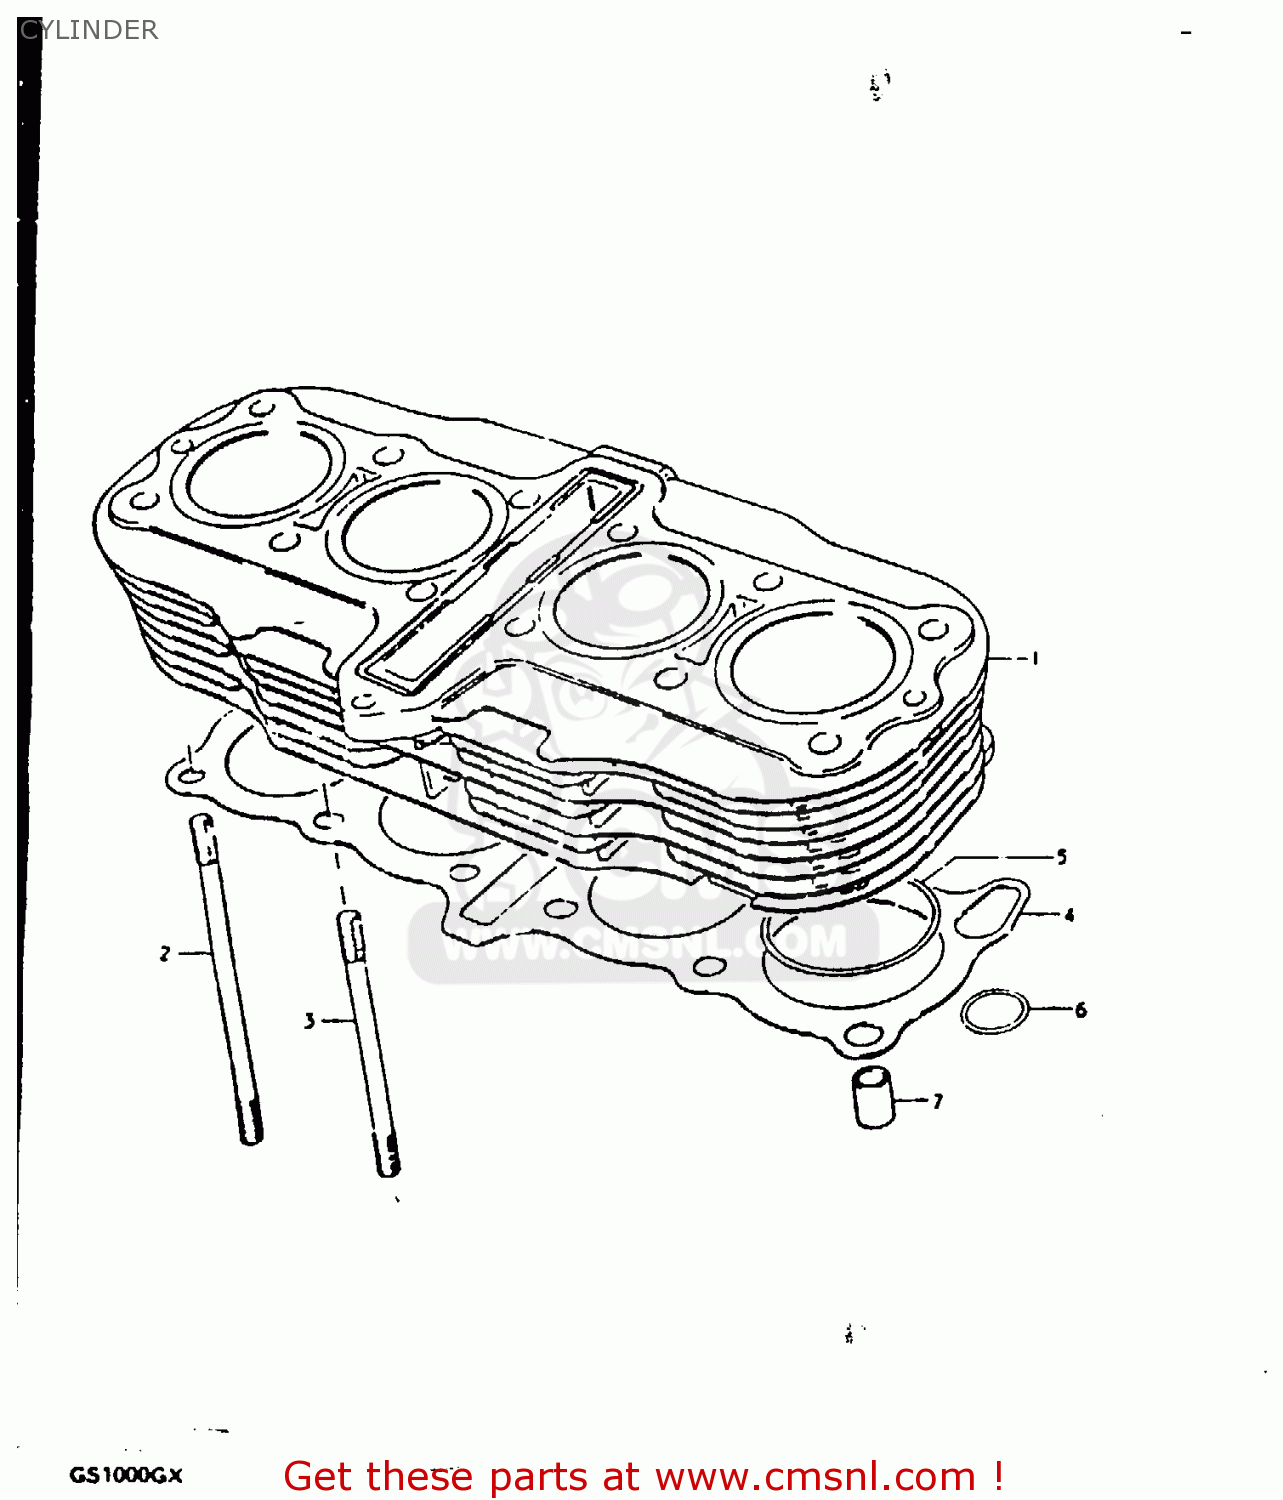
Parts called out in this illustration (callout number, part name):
1	CYLINDER
2	BOLT,STUD
3	STUD
4	GASKET,CYLINDER (MCA)
5	O RING(D:2,ID:74)
6	O RING(D:3.05)
7	PIN
